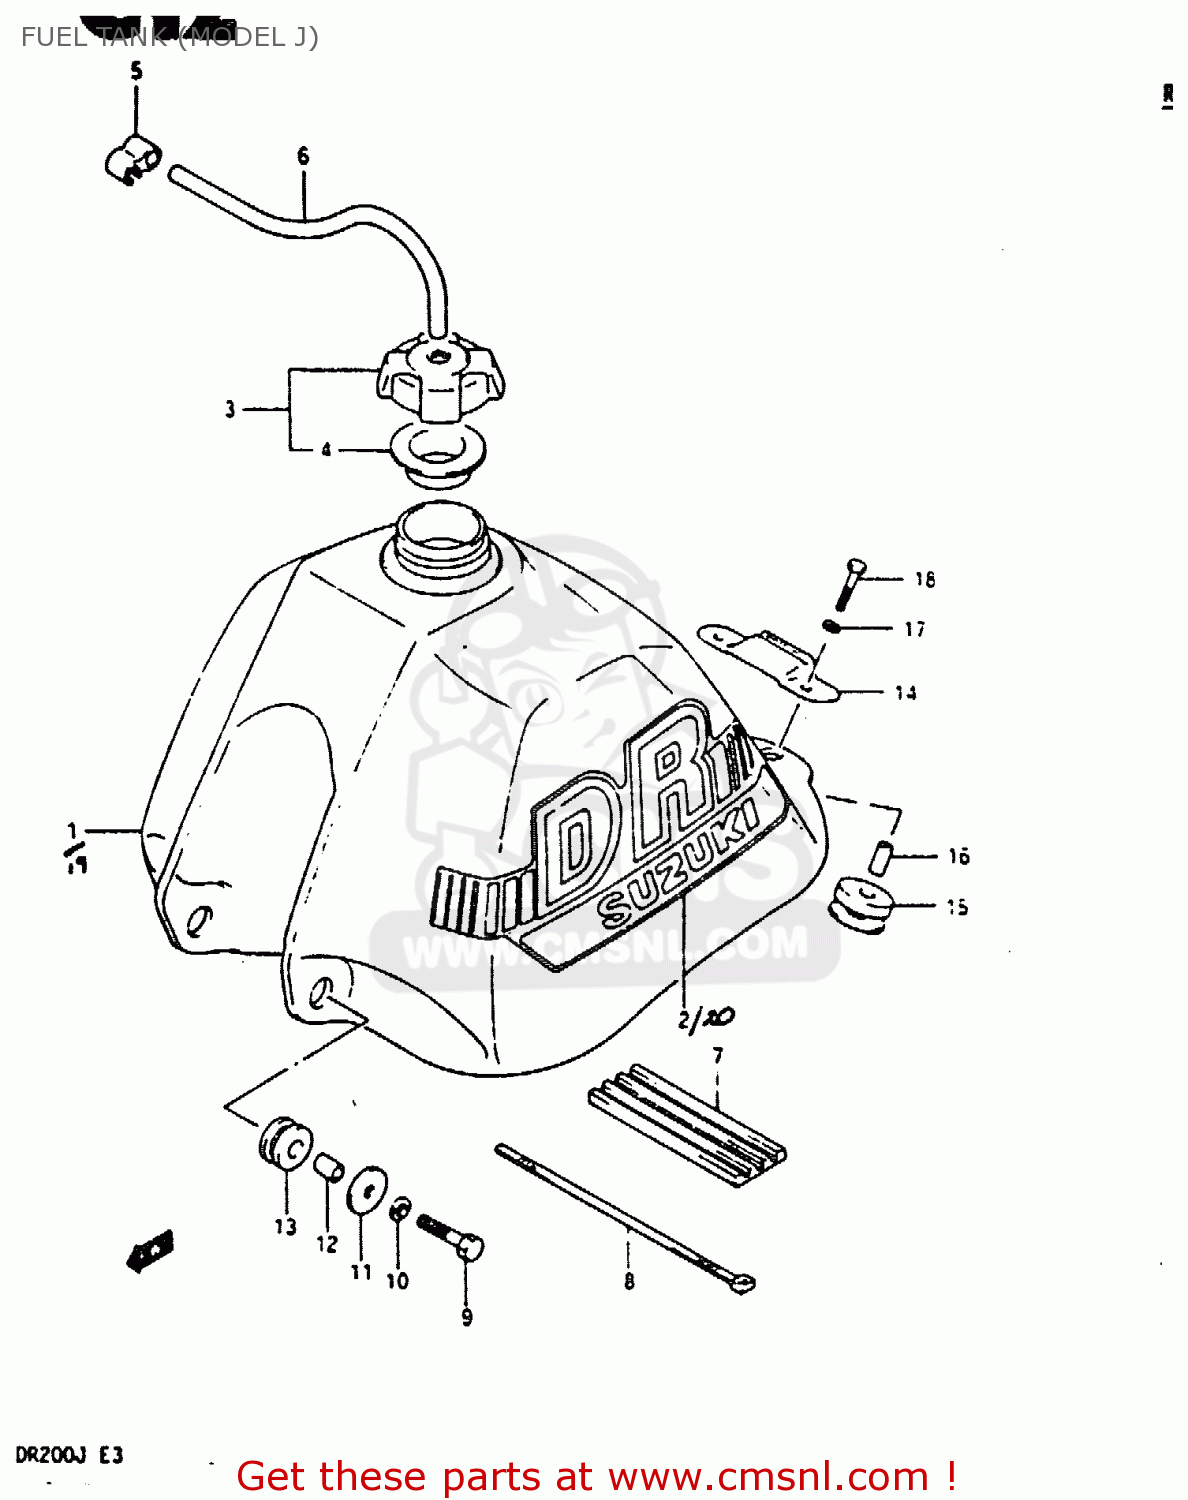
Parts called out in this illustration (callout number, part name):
1	TANK ASSEMBLY,FUEL
2	TAPE SET,FUEL TANK STRIPE
3	CAP SET,FUEL TANK
4	GASKET,FUEL TANK CAP (NAS)
5	CLAMP,FUEL TANK BREATHER HOSE
6	HOSE
7	CUSHION,FUEL TANK UPR FR
8	CLAMP
9	BOLT
10	LOCK WASHER
11	WASHER (8.5X29X1.6)
12	SPACER (8.8X12X13.5)
13	CUSHION
14	PLATE,SEAT FR HOOK
15	CUSHION
16	SPACER
17	WASHER,LOCK
18	BOLT
19	FUEL TANK
20	TAPE SET
21	BOLT
